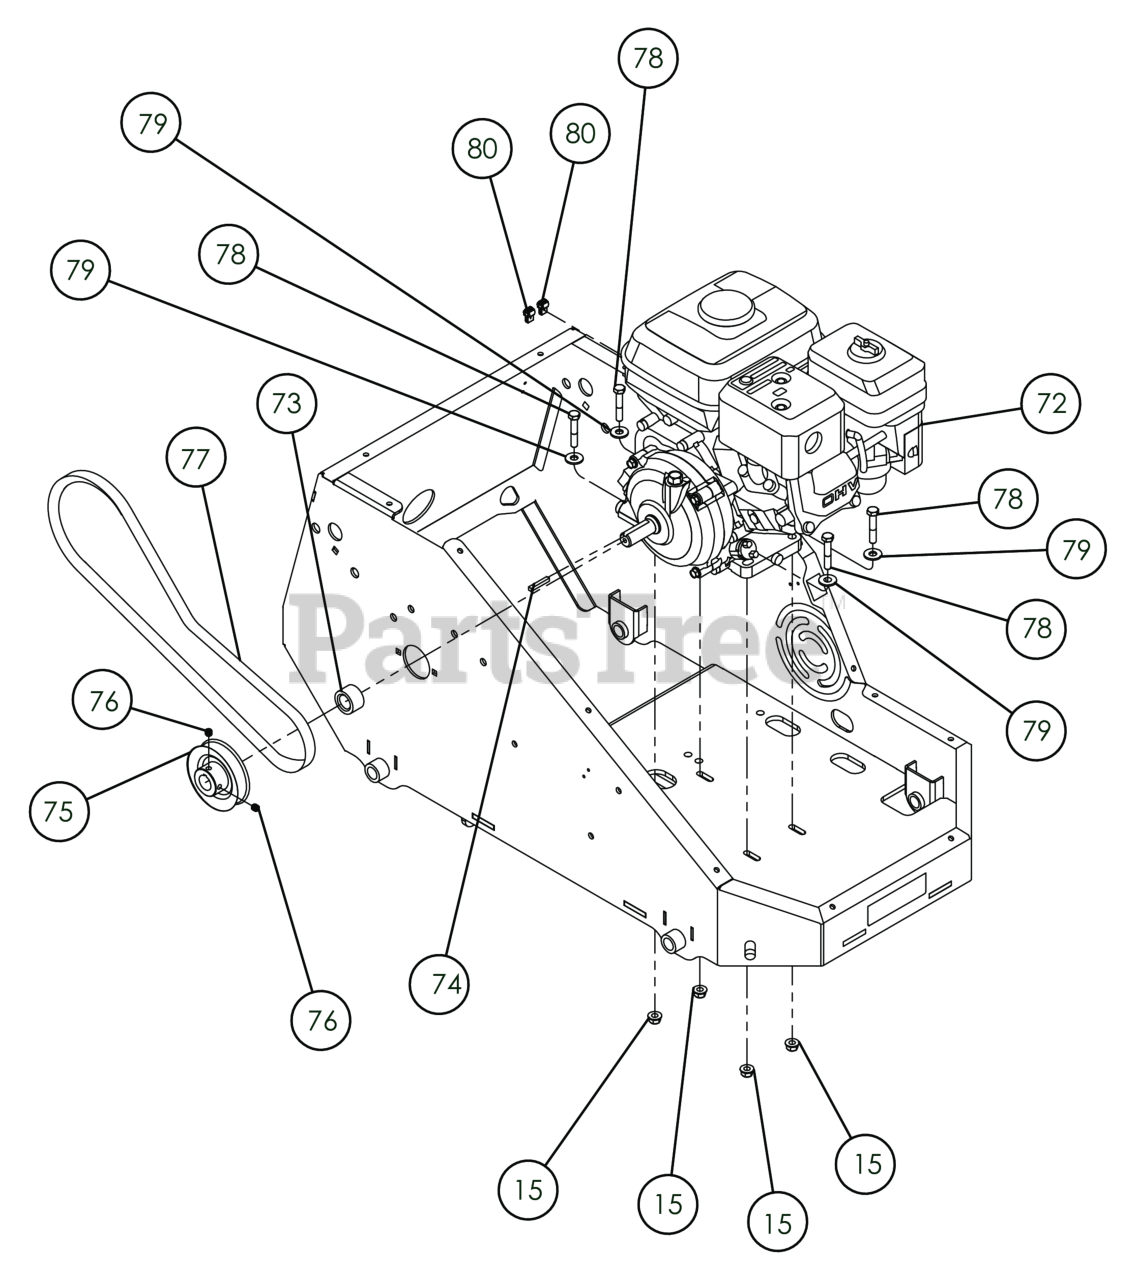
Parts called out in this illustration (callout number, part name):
15	NUT-HEX-NYLK, FLG .3125-18 ZP
72	ENGINE, VANGUARD 203CC W/6:1 AT 3
73	SPCR, ENG  SHAFT VAN PL18
74	KEY 3/16" SQ X 1 1/4"
75	PULLEY, ENGINE
76	SCREW SET 5/16"-24NF X 5/16"
77	BELT BLADE DRIVE FM
78	SCREWCAP 5/16"-18X1 3/4" HCS ZP
79	WASHER 5/16" FLATWASHER Z/P
80	TERMINAL 18-14 BLUE T-TAP
